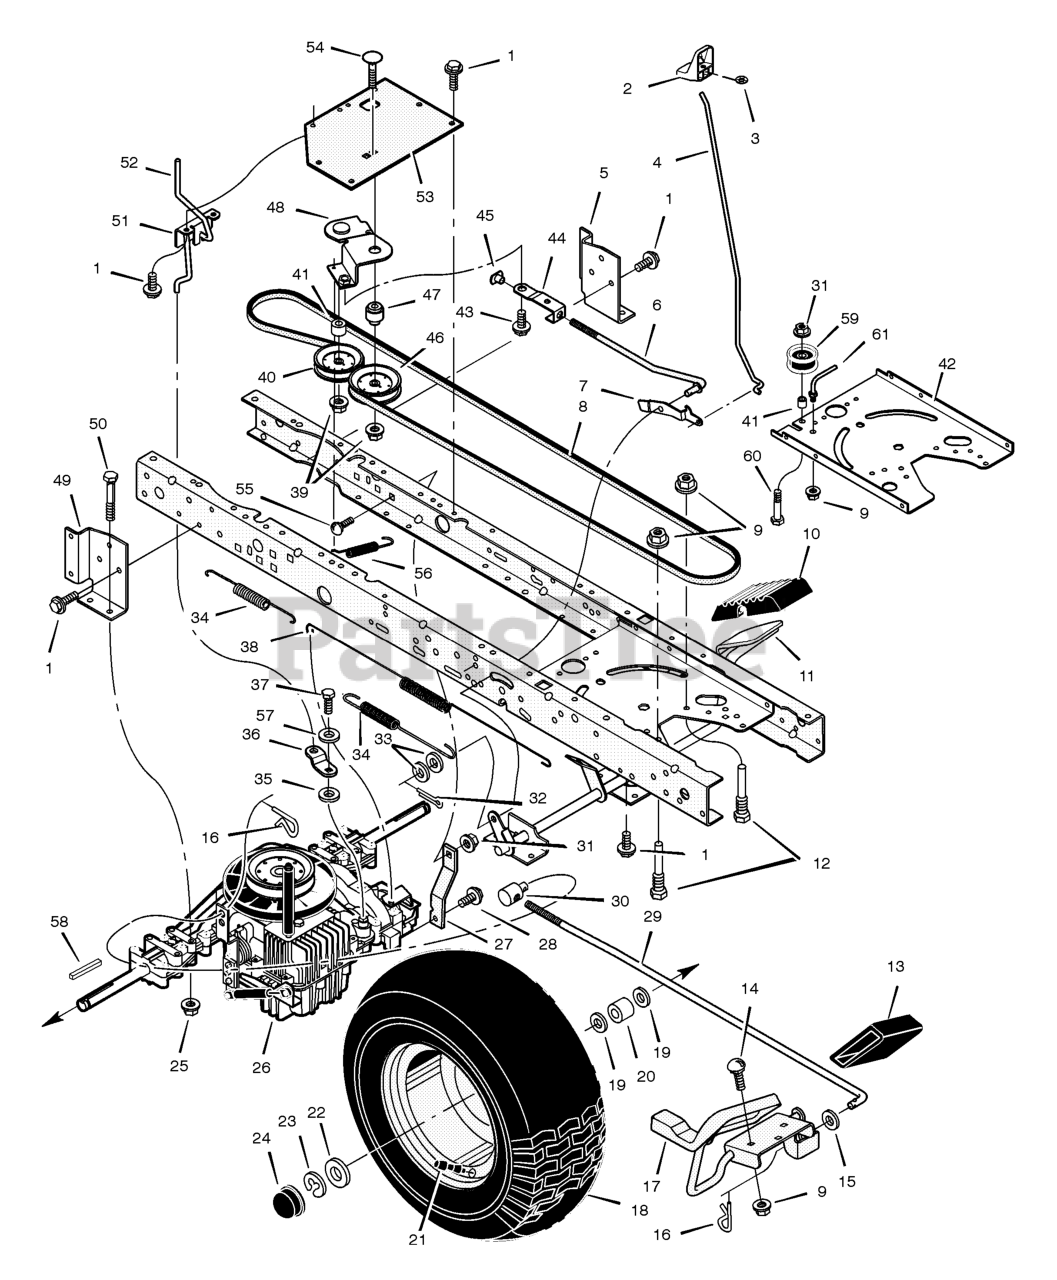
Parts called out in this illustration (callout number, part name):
2	Knob, Parking Brake
3	Nut, Push
4	Rod, Parking Brake
5	Bracket, Left Transaxle
6	Rod, Clutch
7	Latch, Parking Brake
8	V-Belt, Drive
9	Nut, Flange
10	Pad, Brake/Clutch
11	Rod Assembly, Clutch/Brake
12	Screw, Guide
13	Pad, Pedal
14	Bolt, Carriage
16	Pin, Hair
17	Pedal Assembly, Hydro
18	Wheel & Tire Assembly
20	Spacer
21	Stem, Valve
24	Cap, Hub
25	Nut, Centerlock
26	Transaxle **
27	Strap, Torque
29	Rod, Control
30	NUT, Adjusting, 1/2-13
31	Nut, Centerlock
32	Pin, Cotter
34	Spring, Extension
36	ARM, Disconnect
37	Capscrew
38	Spring, Brake
39	Locknut, Flange
40	Pulley, Idler
42	Plate, Steering Mount
43	Bolt, Shoulder
44	Link, Clutch
45	Nut, Tee
46	Pulley, Idler
47	Bushing, Pivot
48	Arm Assembly, Idler
49	Bracket, Right Transaxle
50	Bolt, Hex
51	Bracket, Disconnect
52	Rod, Disconnect
53	Bracket, Idler Pivot
54	Bolt, Carriage
55	Bolt, Carriage
56	Spring, Clutch
58	Key, Square
59	Pulley, Idler
60	Bolt
61	Screw, Belt Guide
